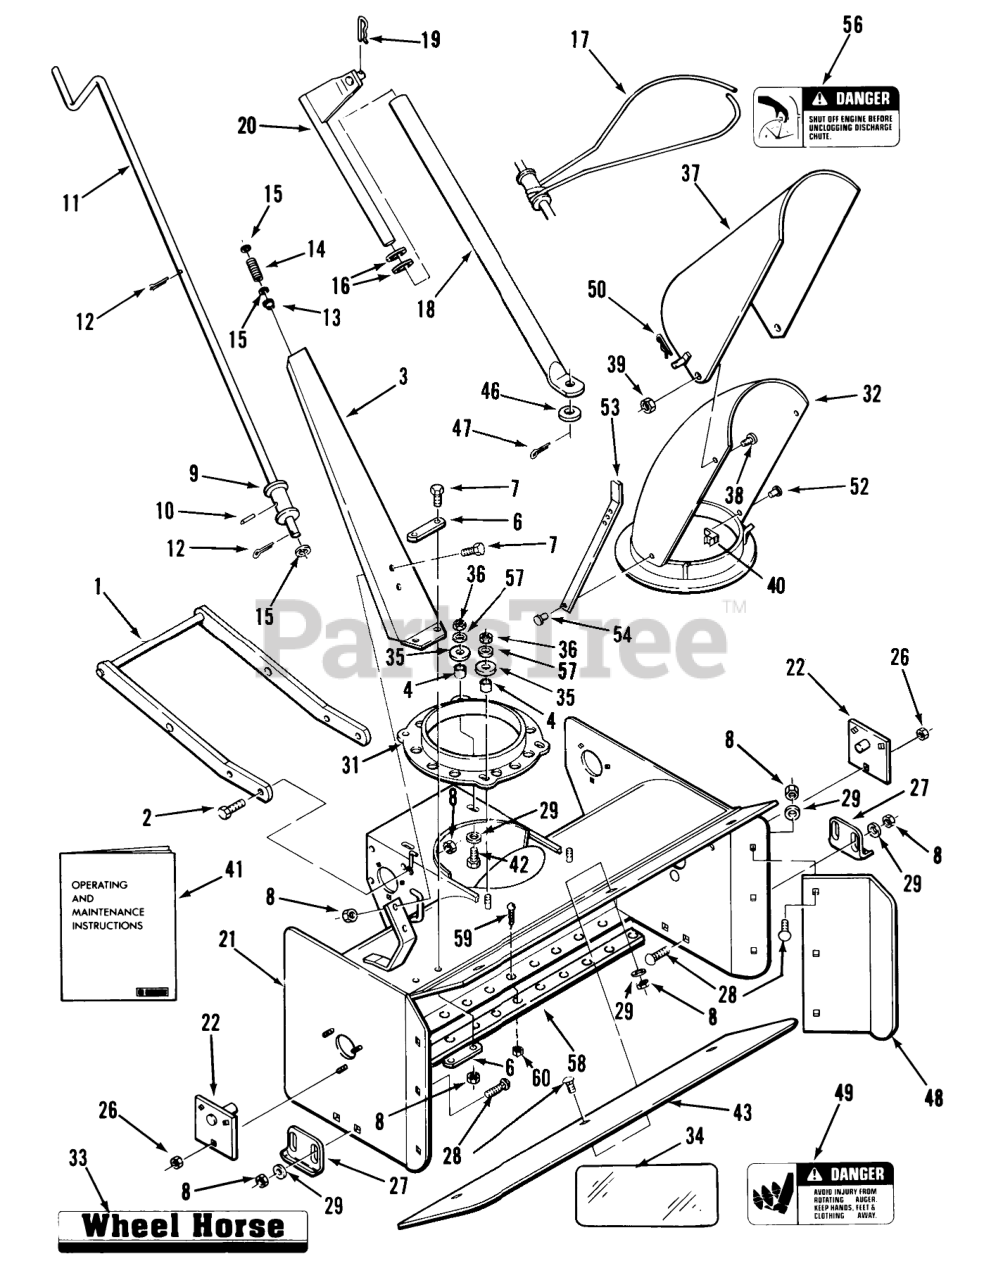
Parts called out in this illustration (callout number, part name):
1	Frame-Mounting
2	Bolt
3	Crank Support
4	SPACER
6	Bar-Reinforcing
7	Bolt
8	Nut
9	ASSY TUBE CRANK R
10	ROLL PIN 1/4 X 1-1/4
11	CRANK R
12	Pop Rivet
13	NYLINER BUSHING
14	SPRING-COMPRESSION
15	Washer
16	Washer
17	CABLE
18	ASSY LIFT TUBE R
19	Hairpin Cotter
20	Lid Rod
21	Wrapper
22	Plate
26	Nut
27	Skid
28	Bolt
29	Washer
31	COLLAR
32	Shroud (includes items 53 & 54)
33	DECAL WHEEL HORSE
34	DECAL-OVERLAY
35	WASHER
36	NUT
37	Deflector
38	MACH. SCREW
39	Nut
40	CLAMP
41	Operating and Maintenance Instructions
42	Bolt
43	Plate
46	WASHER
47	Cotter Pin
48	Plate
49	DECAL DANGER
50	Hairpin
52	RIVET-4
53	ARM R
54	RIVET
56	DECAL DANGER
57	WASHER
58	Reversible Scraper
59	Bolt-Carriage
60	Nut
